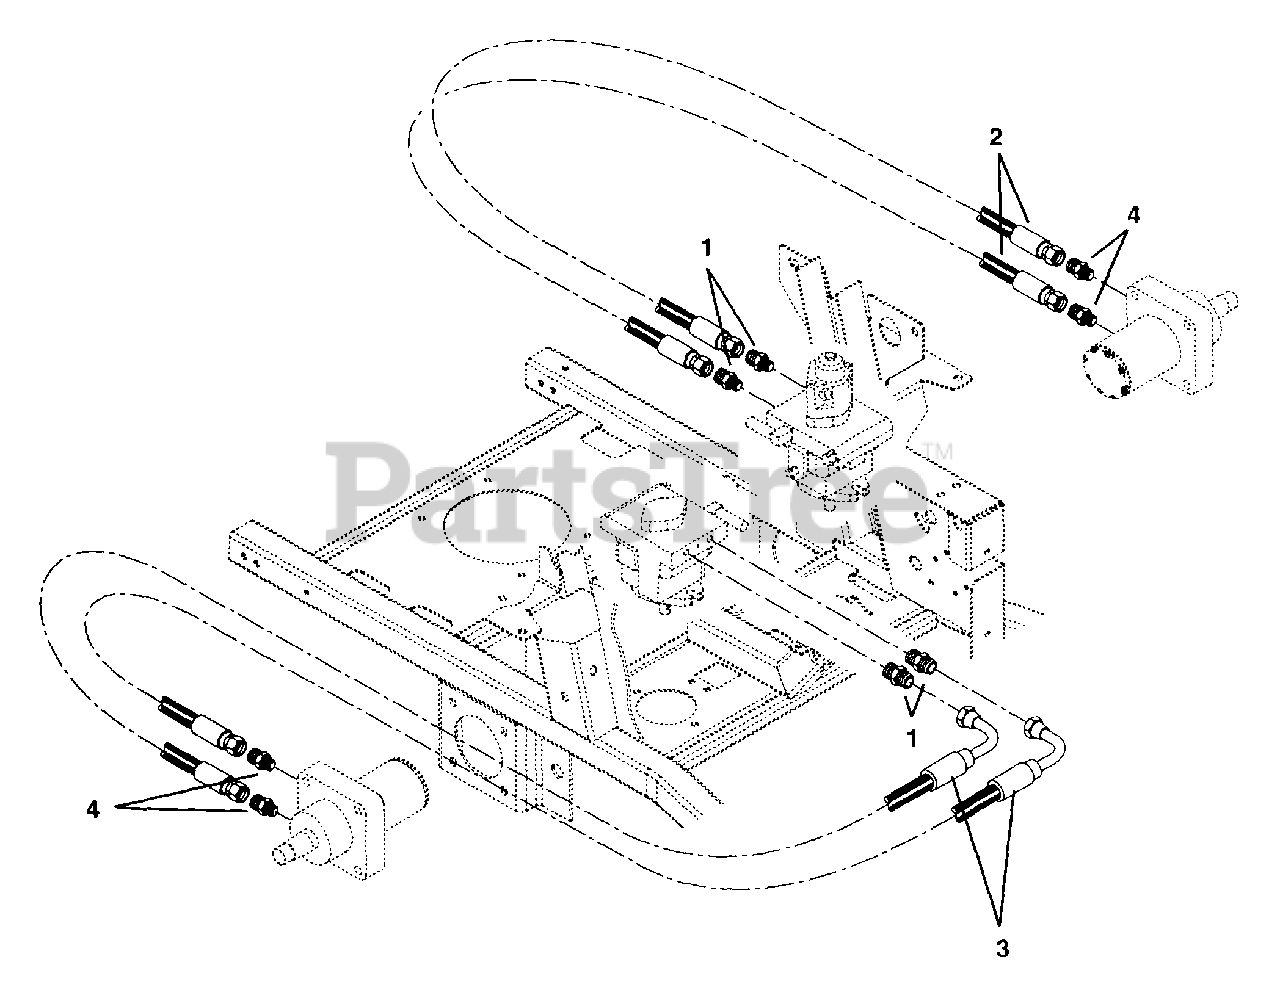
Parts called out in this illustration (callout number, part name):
1	Adapter-Hydraulic Steel .75 to .75
2	Hose-Hydraulic .50 18.75 Long
3	Hose-Hydraulic .50 x 29.50 Long
4	Adapter-Hydraulic Steel 7/8 to 3/4
